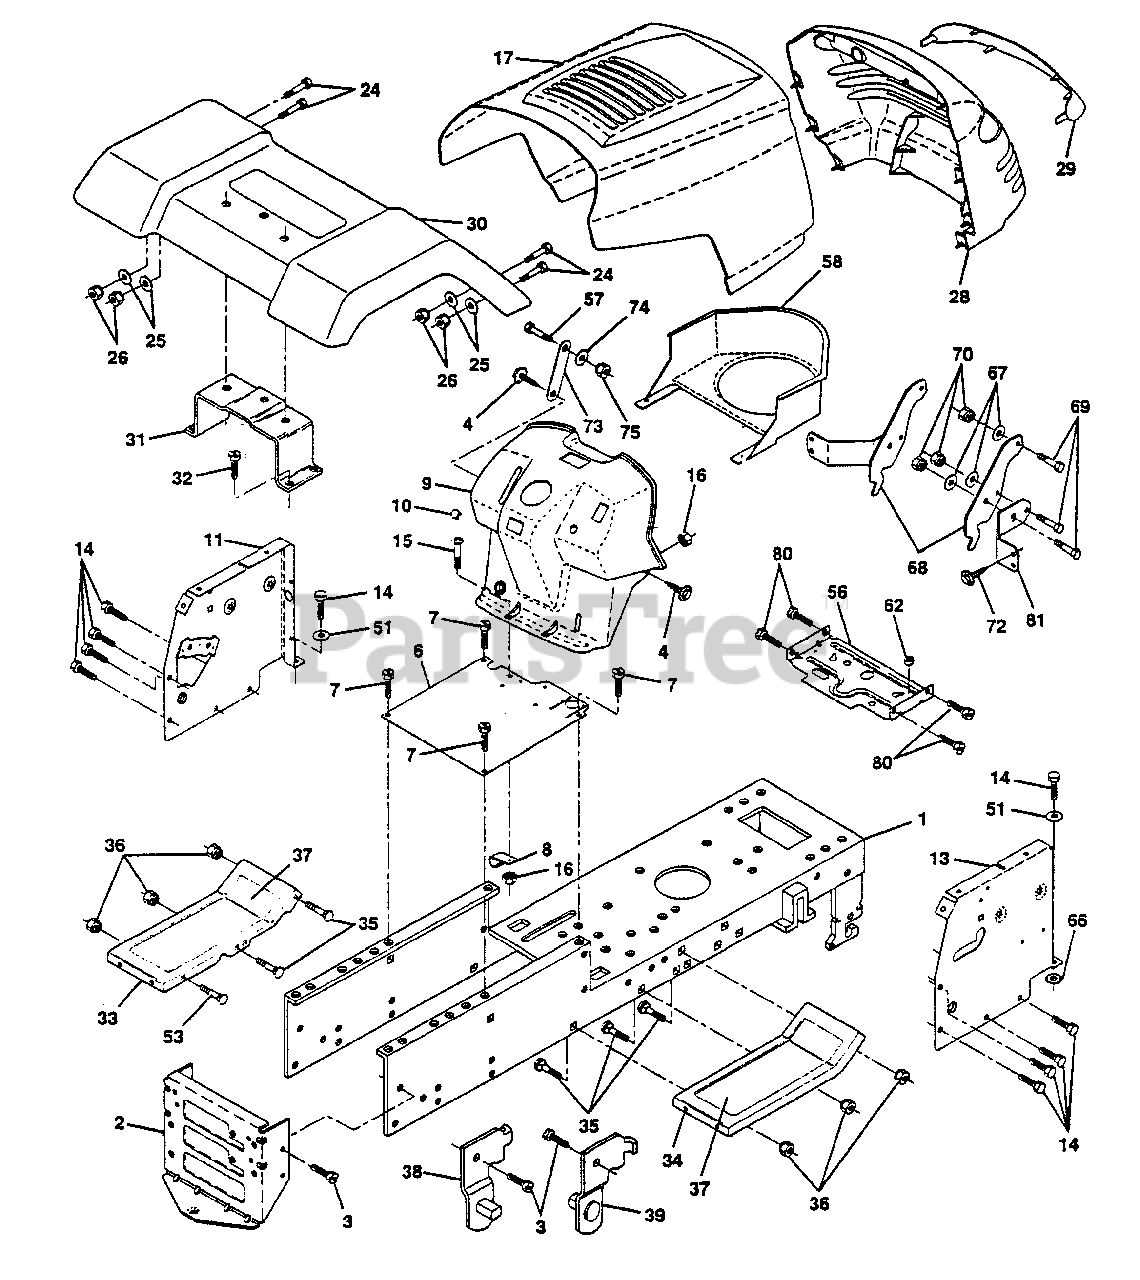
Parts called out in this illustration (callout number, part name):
1	Chassis Weldment 11 ga
2	Drawbar, Stretch
3	Screw Thdrol 3/8-16x3/4 Ty-tt
4	Screw Hexwsh. Thdrol 1/4-20 x 3/4
6	Saddle LT Fender Shift
7	Screw Thdrol 3/8-16x3/4 Ty-tt
8	Clip Line Fuel 13/32 Mtg Hole
9	Dash Private Label
10	Plug Button
11	Panel Pnt Dash Lh
13	Panel Dash Rh Weldment
14	Screw Thdrol 3/8-16x1/2 Ty-tt
15	Screw Mach Cr 1/4-20 uncx3/4
16	Nut Keps Hex 1/4-20
17	Hood Paint Steel Private Label
24	Bolt Fin Hex 3/8-16unc X 1 Gr. 5
25	Washer 13/32 X 13/16 X 12 Ga
26	Nut Lock Hex W/Ins 3/8-16 Unc
28	Grille Private Label
29	Lens Grille Private Label
30	Fender Pnt
31	Bracket Pnt Fender
32	Screw Thdrol 3/8-16x3/4 Ty-tt
33	Footrest Pnt Lh
34	Footrest Pnt Rh
35	Bolt Rdhd Sht Sqnk 3/8-16 X3/4
36	Nut Hex Lock W/Insert 3/8-16 Unc
37	Pad Footrest
38	Bracket, Asm. Pivot, L.H., Mower Rear
39	Bracket, Asm. Pivot, R.H., Mower Rear
51	Washer 13/32 x 3/4 x 16 Ga.
53	Bolt Carriage 3/8-16 x 1
56	Support Battery
57	Screw Hex 1 /4-20 x 3/4
58	Air Duct P/L
66	Washer Lock Ext. Tooth 3/8
67	Washer 9/32 x 7/8 x 16 Ga.
68	Hinge Pickoff Hood
69	Bolt Hex Hd 1/4-20
70	Nut, Crownlock 1/4-20
72	Screw Lock Spider #8 x 7/8
74	Washer 9/32 x 7/8 x 16 Ga.
75	Nut Lock Hex W/Ins 1/4-20
80	Screw Thdrol 5/16-18 X3/4
81	Bracket, Grill
